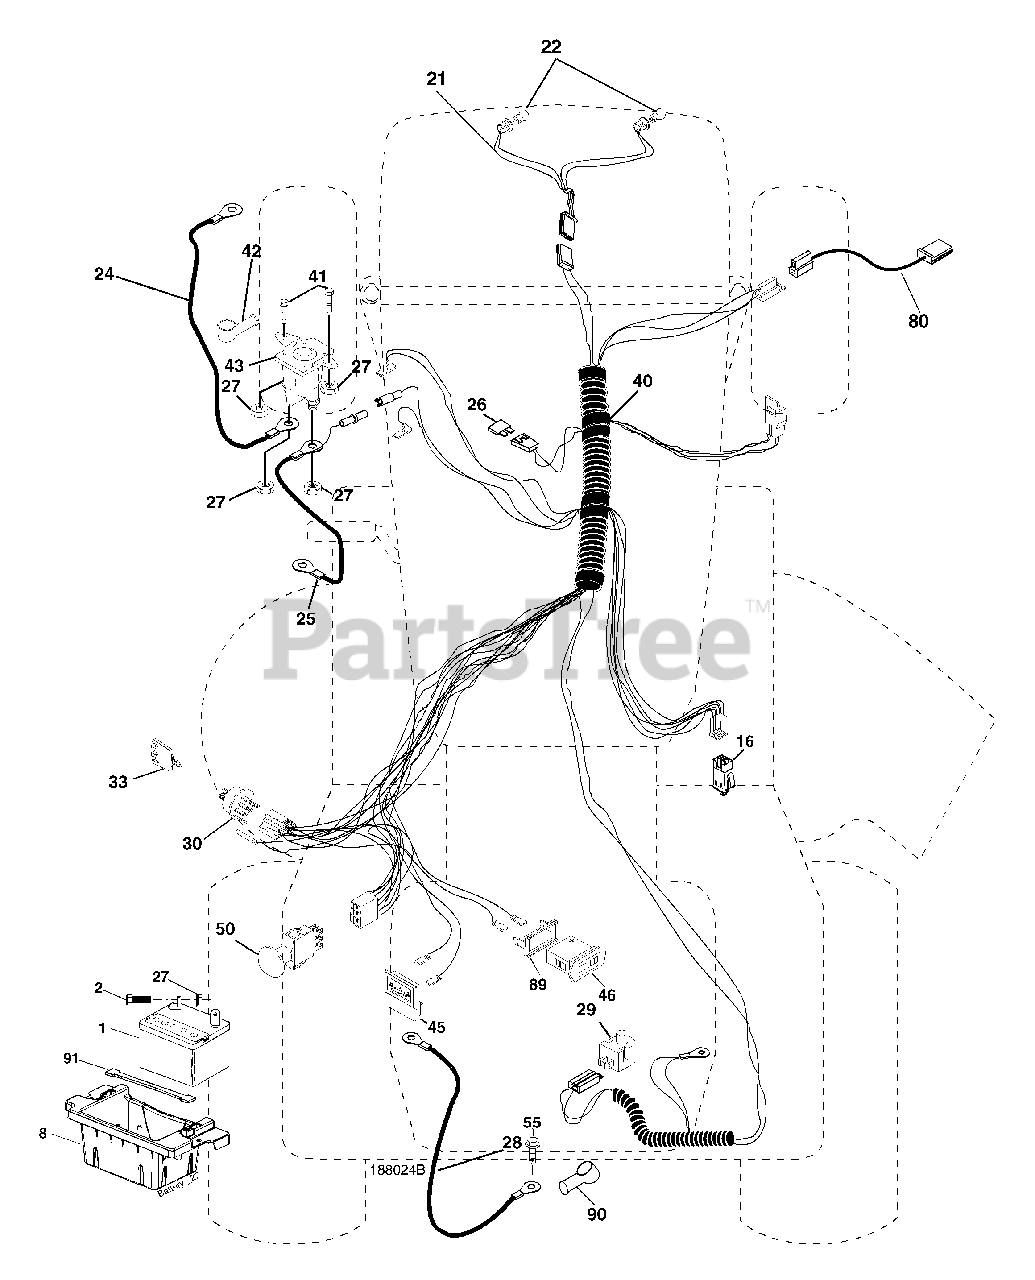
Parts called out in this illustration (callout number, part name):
1	Battery 12 Volt 35 AMP
2	Bolt Hex Hd 1/4-20 unc x 3/4
8	Box Battery
16	Switch Interlock Push-In
21	Harness Asm Light W/4152j
22	Bulb Light #1156
24	Cable Battery 6 Ga. 22" red w/16 wire
25	Cable Battery 6 Ga. 11" red
27	Nut Keps Hex 1/4-20 unc
28	Cable Ground 6 Ga. 21" black
29	Switch Plunger Nc Gray
30	Switch Ign
33	Key Ign Molded Generic
40	Harness Ign.
41	Bolt Blk Fin Hex 1/4 - 20 x 1/2
42	Cover Terminal Red
43	Solenoid
45	Ammeter Rectangular 15 Amp
46	Meter Hour
50	Switch PTO
55	Screw Thdrol 5/16-18 x 1-1/2 Tyt
80	Harness Clutch Evx
89	Bracket Snap-In Hourmeter
90	Cover Terminal Battery
91	Strap Battery
